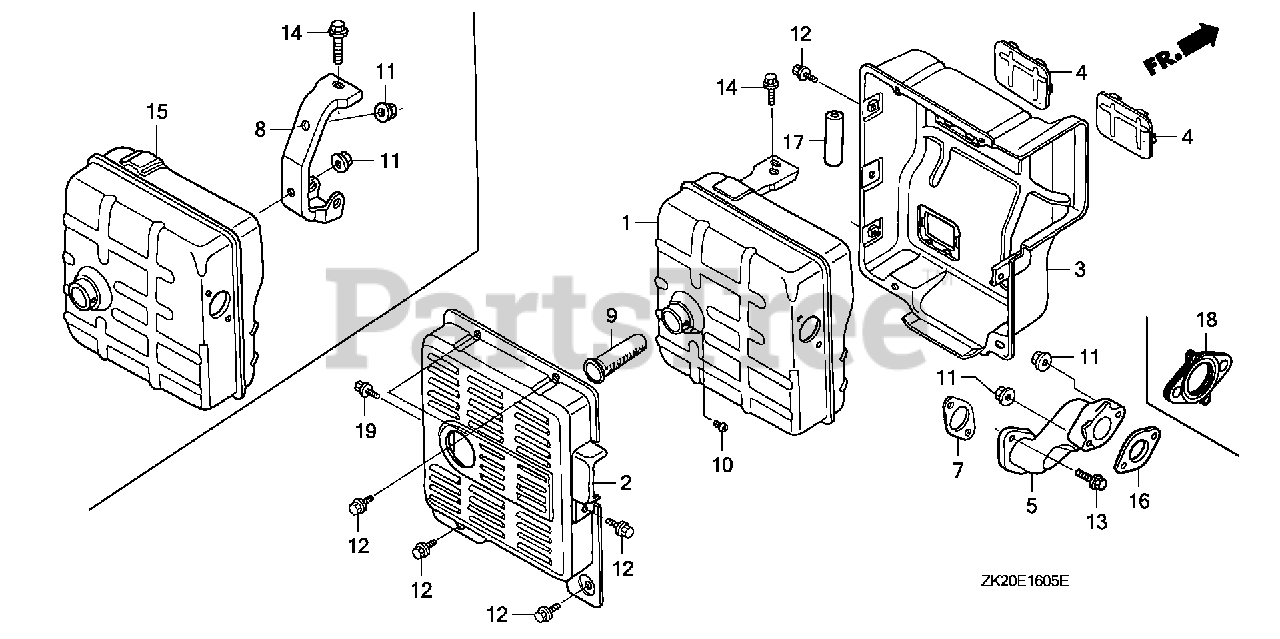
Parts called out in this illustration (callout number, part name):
1	MUFFLER (SANKEI)
2	PROTECTOR, MUFFLER (OUTER)
3	PROTECTOR, MUFFLER (INNER)
4	SEAL, MUFFLER PROTECTOR
7	GASKET, EX. PIPE
9	ARRESTER, SPARK
10	SCREW, TAPPING (4X8)
11	NUT, FLANGE (8MM)
12	BOLT, FLANGE (6X12)
13	BOLT, FLANGE (8X20)
16	GASKET, EX. PIPE
19	BOLT, FLANGE (6X12)
